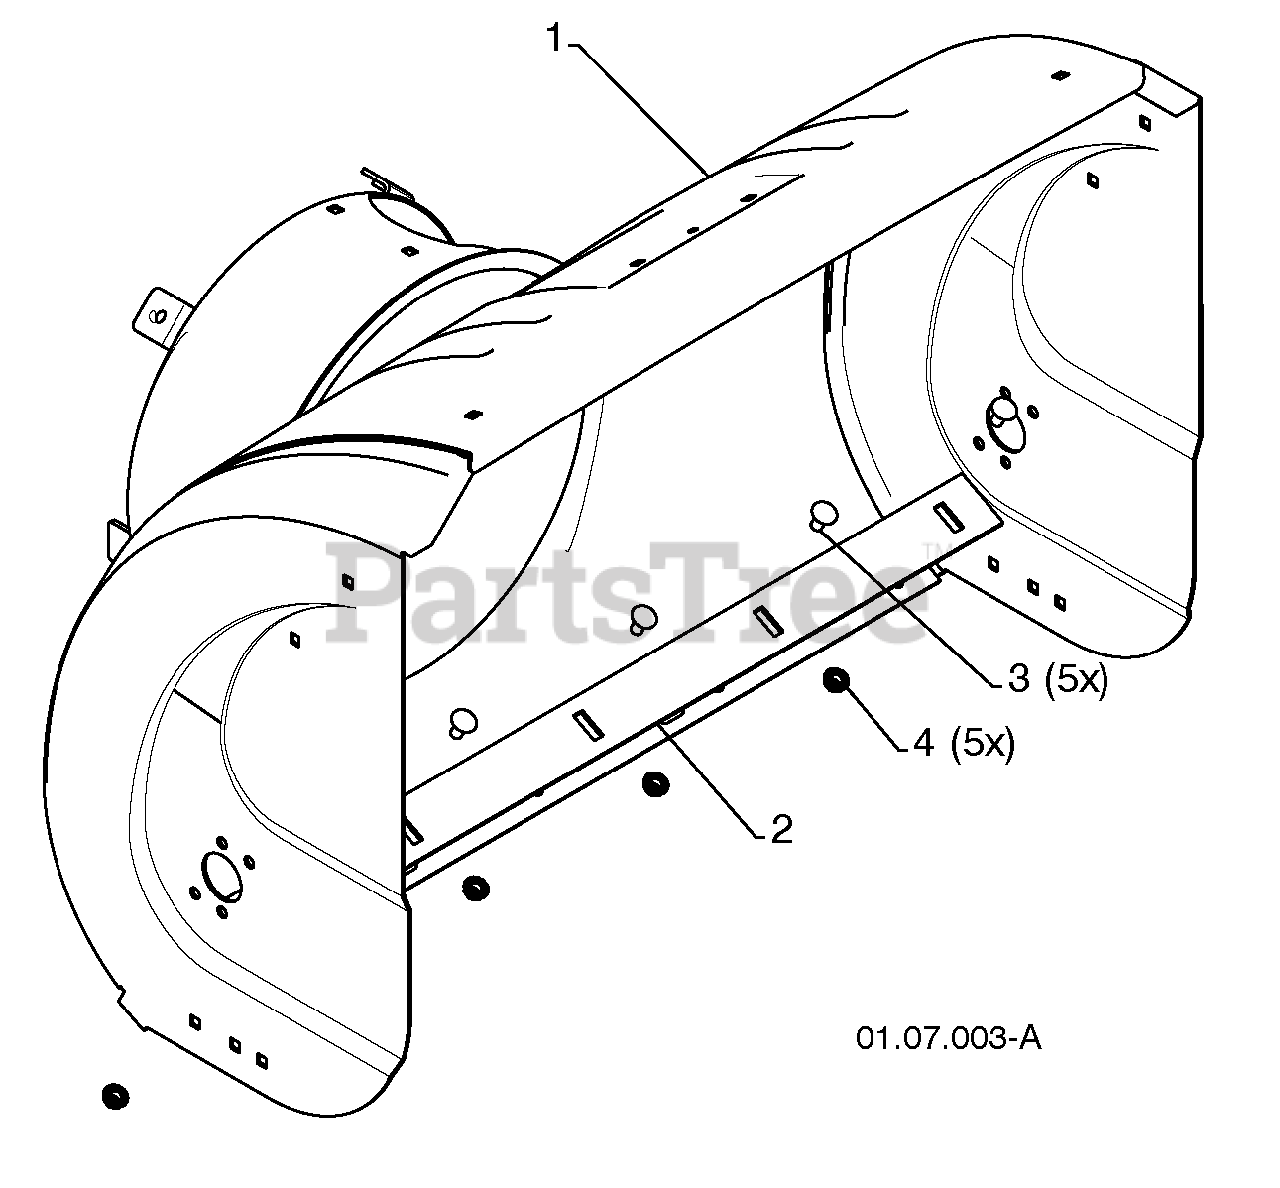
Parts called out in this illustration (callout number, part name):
1	AUGER HOUSING
2	SCRAPPER BAR
3	CARRIAGE BOLT 5/16-18 X .625
4	NUT 5/16-18
